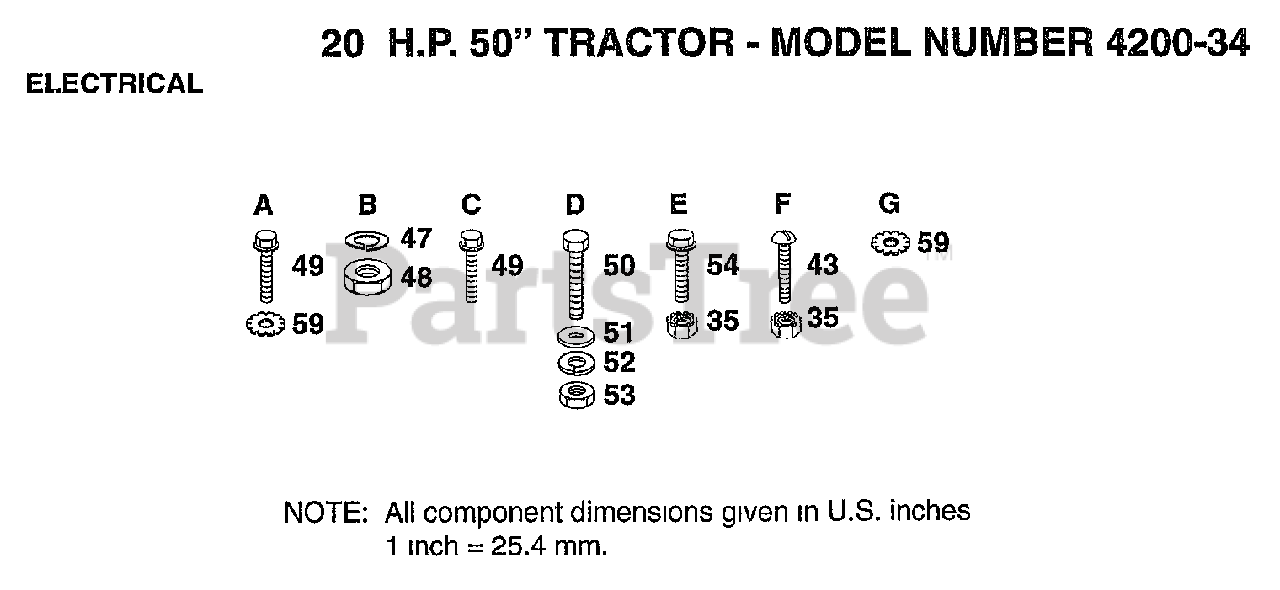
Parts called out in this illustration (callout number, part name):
35	"NUT,KEPS"
48	NUT
49	SCREW
50	BOLT LT
51	WASHER
52	LOCKWASHER
54	SCREW
59	LOCKWASHER
